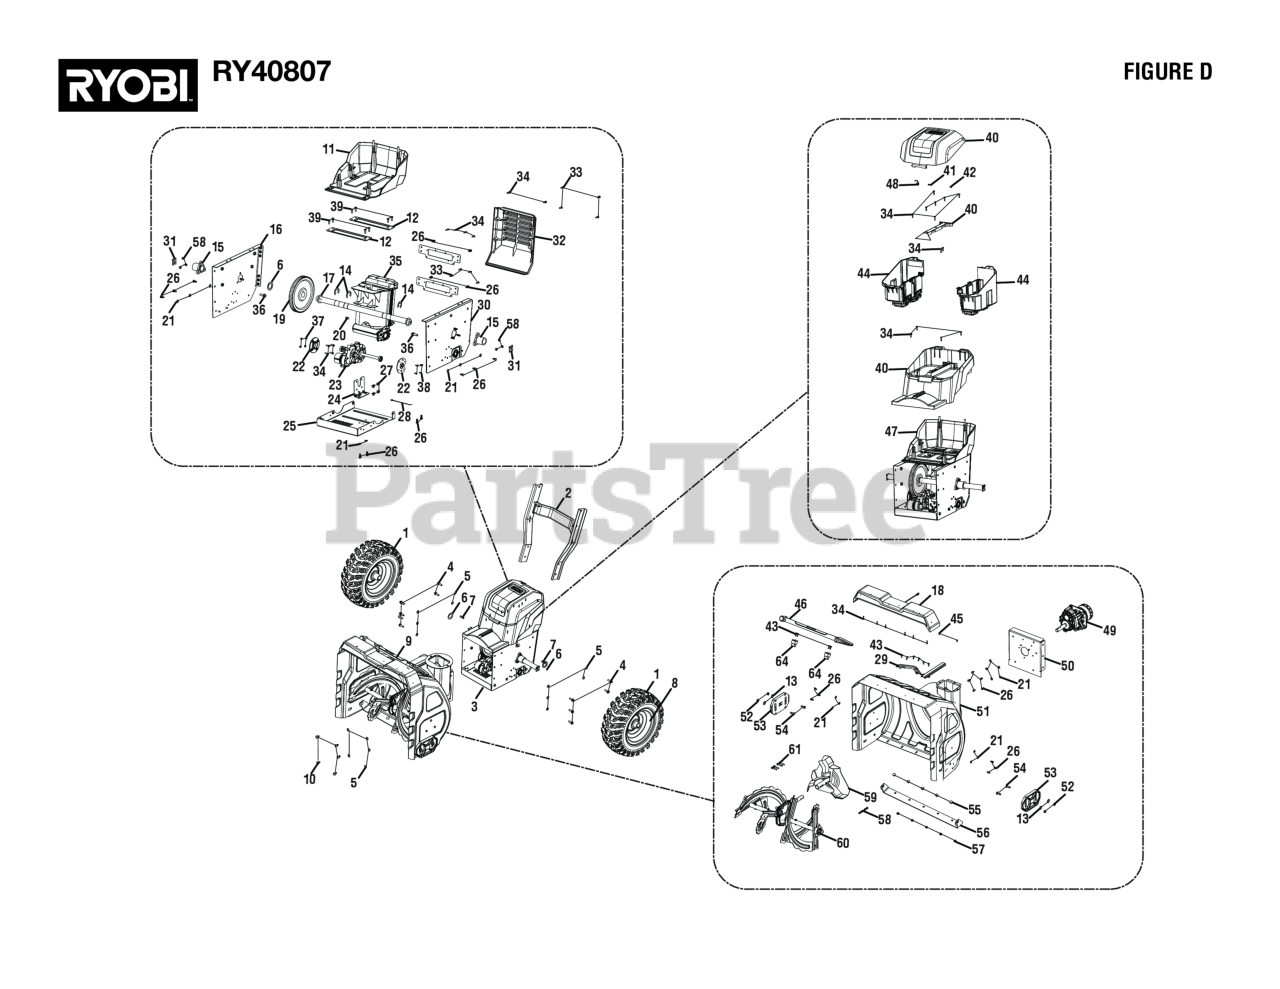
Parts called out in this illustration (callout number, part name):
1	16 in. Tire Wheel Assembly
2	Handle Level Adjustment
3	Battery Box Assembly
4	Screw (M8 x 25 mm)
5	Wave Washer
6	Washer (OD1.031 x ID1.57 x 0.60t)
8	16 in. Pneumatic Wheel
9	Lower Deck Assembly
10	Screw (M8 x 16 mm, T40 Hex Hd.)
11	Battery Box Base
12	Cross Strut
13	Washer (ID9.8 x OD30 x 3t)
15	Axle Bushing
16	Side Panel (Right)
18	Led Light Bar
19	Big Output Gear
21	Washer (ID6.2 x OD15 x 0.08t)
22	Bearing Support Assembly
23	Gear Box Assembly
24	Transmission Bracket
25	Bottom Panel
26	Screw (M6 x 14 mm)
27	Screw w/Washer (M4-18 x 10 mm, T20 Torx Pan Hd.)
29	Wire Cover Assembly
30	Side Panel (Left)
31	Spring Plate Fastener
32	Black Panel
33	Bolt (M5 x 14 mm)
34	Screw (M4 x 18 mm, T20 Torx Pan Hd. S.T.)
35	Heat Sink Assembly
36	Screw (M8 x 25 mm)
38	Screw (M4.2 x 12 mm, T20 Torx Pan Hd.)
39	Screw (M6 x 17 mm)
40	Battery Cover Assembly
41	Compression Spring
42	Battery Door Axle
43	Bolt (M5 x 14 mm)
44	Battery Box Assembly Assembly (See Fig. G)
45	Screw (M4 x 10 mm, Pan Hd.)
46	Snow Shovel
47	Chassis Assembly
48	Battery Door Torsion Spring
49	Gearbox Assembly
50	Adaptor Bracket
51	Deck w/Labels
52	Nut (M8 x 6.5 mm)
53	Skid Shoe
54	Screw (M8 x 23 mm)
55	Screw (M8 x 11 mm)
56	Scraper Blade
57	Hex Nut (M8)
58	Lock Nut (M6 x 6 mm)
59	Impeller Welded Assembly
60	Scraper Assembly
61	Screw with Spring Washer (M6 x 35 mm)
